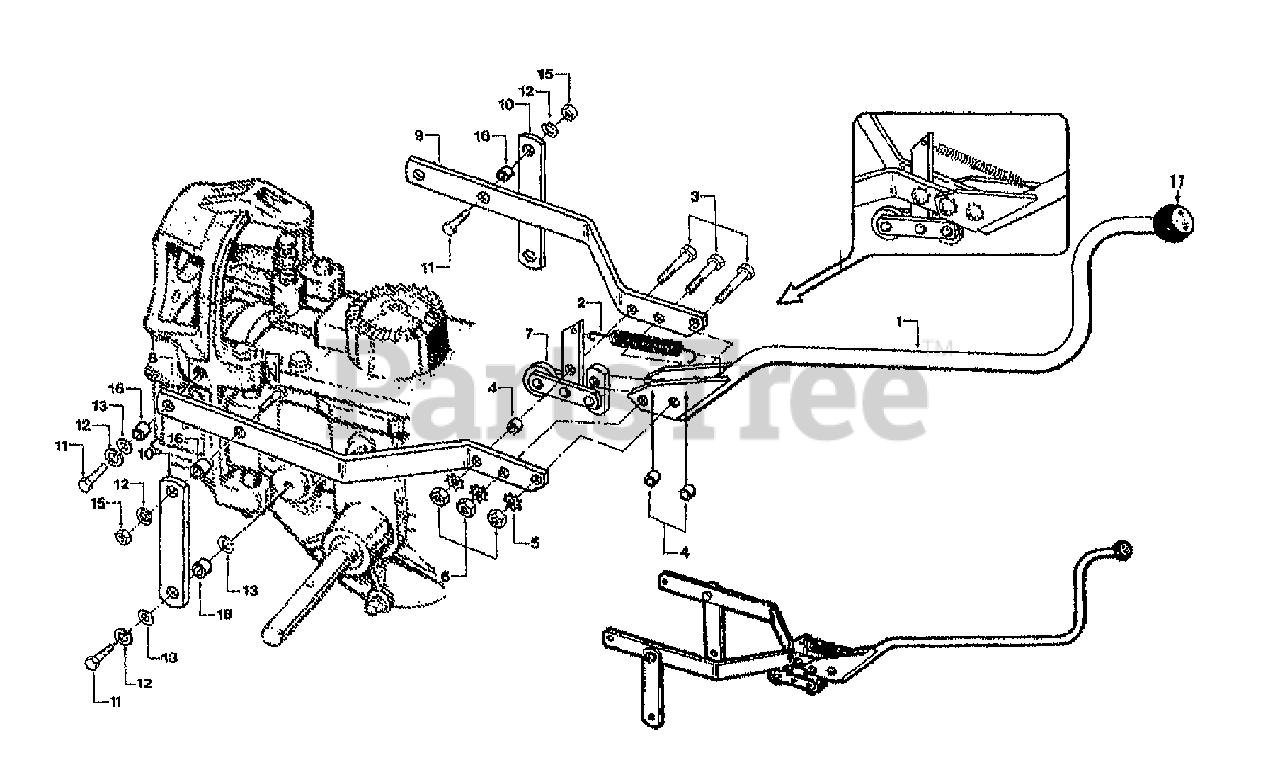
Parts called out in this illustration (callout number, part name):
1	ASSM-FOR/REV LEVER (INCL. KNOB W/DECAL)
2	SPRING-.436 X 3.25
3	SCR-HH 5/16-18X1.5 G5 ZP
4	BUSHING-.5X.316X.375 PM
5	WASHER-LK .312 EXT TOOTH
6	NUT-HEX 5/16-18 ZP
7	ASSM-ROLLER PAINT
8	YOKE-LH RED
9	YOKE-RH RED
10	YOKE-RED 2164
11	SCR-HH 3/8-16X1.0 G5 ZP
12	WASHER-LK .375 @ DEPL
13	WASHER-FLAT 3/8 SAE
14	THIS REF. NO. NOT USED
15	NUT-HEX 3/8-16 ZP
16	BUSHING-.5X.375X.3 (.300")
17	KNOB - NOT AVAIL. SEPARATELY. SEE REF. NO. 1
